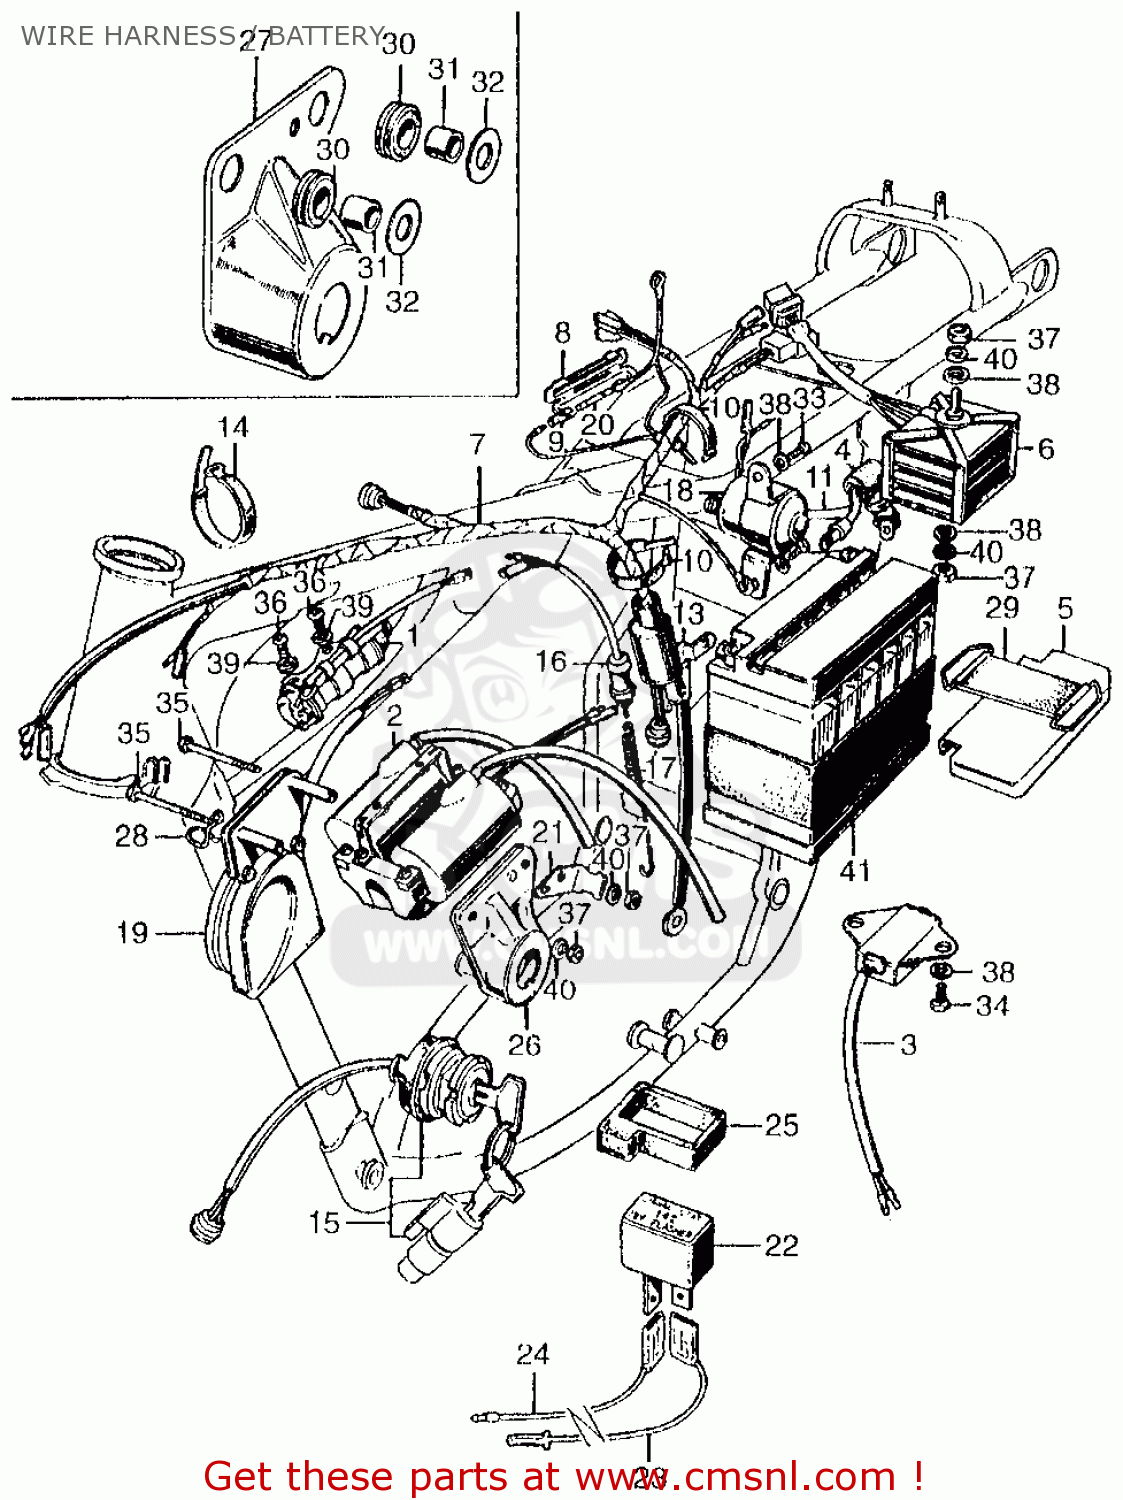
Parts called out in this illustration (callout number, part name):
1	CONDENSER ASSY
2	COIL IGNITION
3	POINTLESS
4	COVER
5	COVER BATTERY
6	RECTIFIER,SILICON
7	HARNESS,WIRE
8	CASE,FUSE
9	CONNECTOR,FUSE
10	BAND,B1 WIRE
11	CABLE,BATTERY
12	COVER,TERMINAL
13	CABLE,EARTH
14	BAND A1,WIRE
15	KEY-SET
16	SWITCH,STOP LAMP
17	SPRING,STOPSWITCH
18	SWITCH MAGNETIC
19	HORN ASSY
20	FUSE,15A
21	SIGNAL STAT
22	STAY
23	SUB-WIRE A
24	CORD B WINKER
25	SUSPENSION,RELAY
26	BRACKET, MAIN SWITCH
27	BRACKET SWITCH
28	CLAMPER CABLE
29	BAND E,BATTERY
30	RUBBER,NU BRACKET
31	COLLAR NO BRACKET
32	WASHER,18MM
33	BOLT,HEX 6X8
34	BOLT,HEX 6X12
35	BOLT,HEX 6X80
36	SCREW,CROSS 5X8
37	NUT HEX 6MM
38	WASHER PLAIN 6MM
39	WASHER,SPG.,5MM
40	WASHER,SPRING,6MM
41	BATTERY ASSY.
